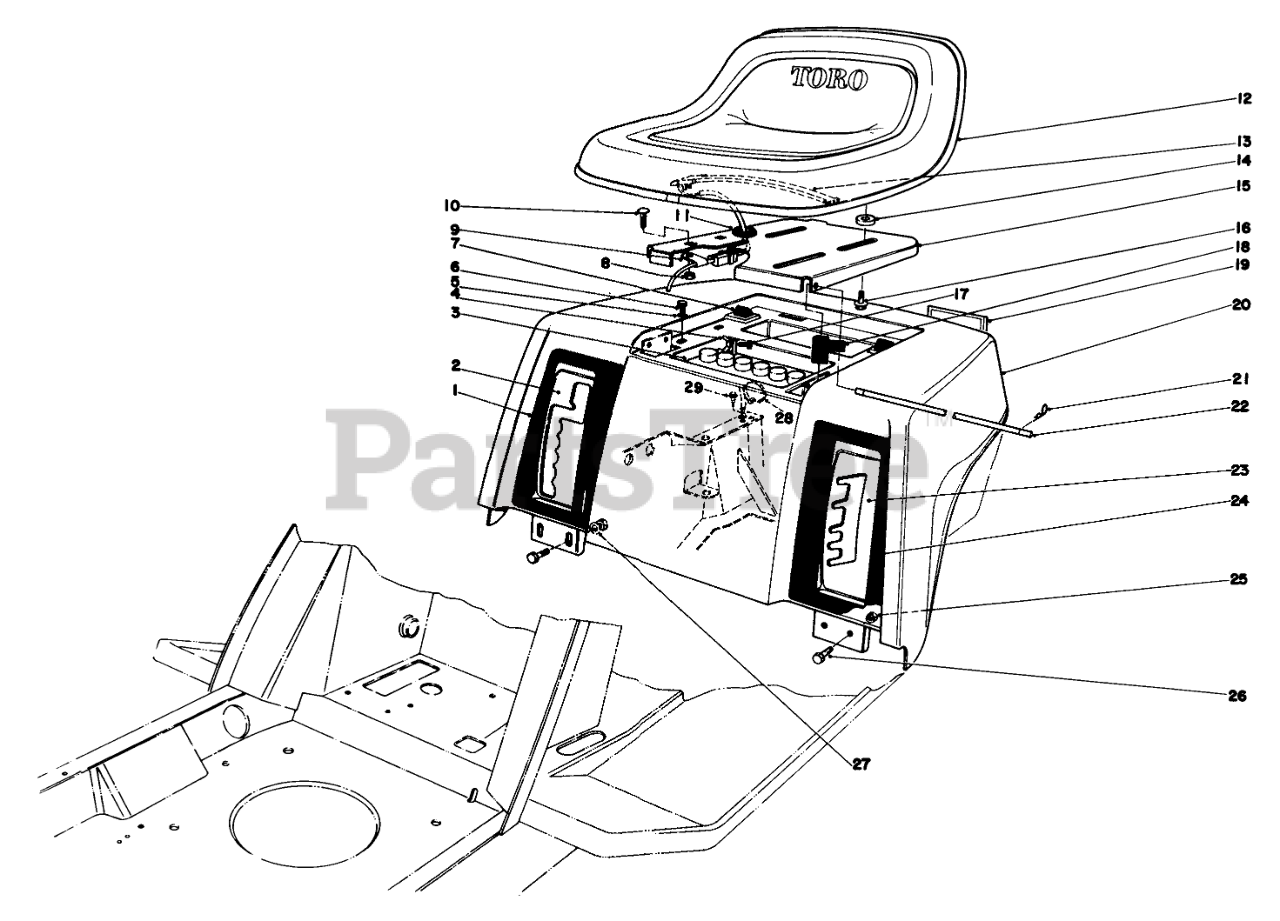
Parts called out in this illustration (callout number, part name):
1	Decal-Transmission
2	DETENT PLATE B
3	Battery
4	NUT-WING
5	WASHER
6	SCREW-HWHTF
7	SEAT BUMPER
8	NUT-KEPS
9	CLAMP
10	SCREW-CARR
11	GROMMET
13	SWITCH-SEAT
14	SPACER-PIN, MOUNTING
15	SEAT SUPPORT R
16	SCREW-HHF
17	SCREW-HH
18	BOOT-TERMINAL
19	REFLECTOR
20	Rear Body Assembly (Incl. Ref. #1 & 24)
21	PIN-COTTER
22	PIVOT-SEAT
23	HOC QUADRANT B
24	HOC DECAL
25	NUT-LOCK, NI
26	SCREW-HH
27	WASHER-PLAIN
28	TIE-CABLE
29	SCREW-HWHTF
